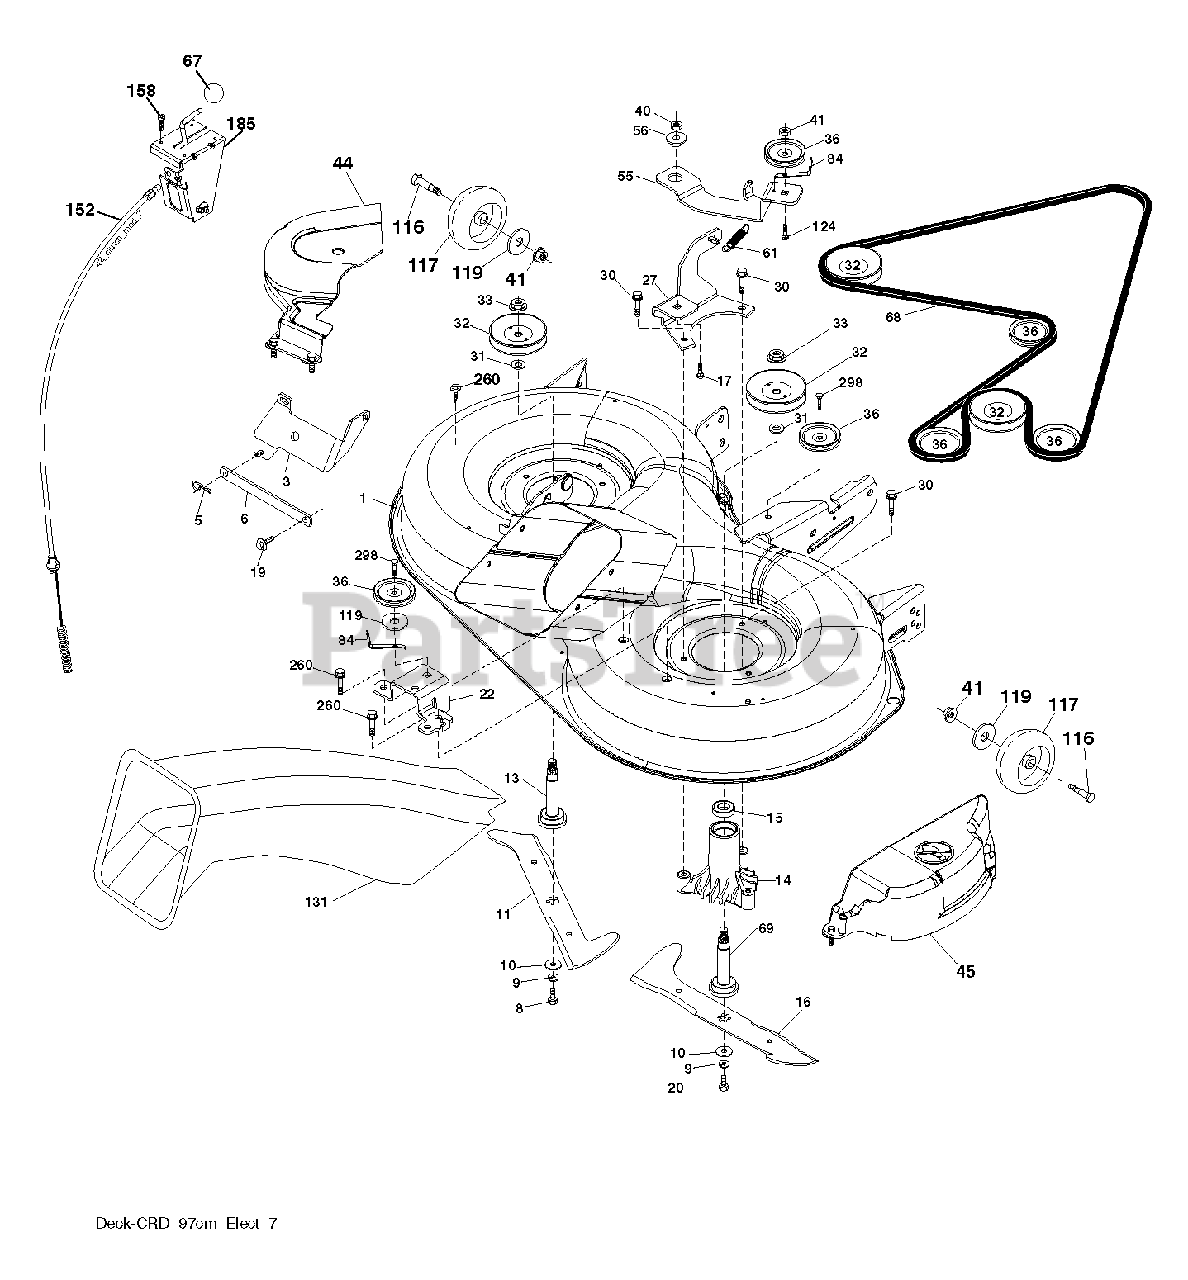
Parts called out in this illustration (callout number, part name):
1	DECK.WLDT.97.CRD.2GWB
3	BRACKET.ASM.BAR.SWAY.CHASS
5	RETAINER-SPRNG RB
6	BAR SWAY
8	Bolt, 3/8-24 X 1.25 Gr8
9	LOCKWASHER
11	BLADE.3N1.LH.CRD.97
13	SHAFT ASM VENT
16	BLADE.3N1.RH.CRD.97
17	BOLT.3/8-14X1.25
19	BOLT SHD 5/16-18
20	BOLT.3/8-24X1.25GR8. LHTHRD
22	BRACKET.SUPT.IDLER.REAR.RH
27	BRACKET.ASM.SUSP.REAR.RH.
30	SCREW, WASHER HEAD
31	WASHER.SPACER.MANDREL
32	PULLEY MANDREL
33	NUT.FLANGE.LOCK.TOP
36	PULLEY.IDLER.4.25
40	LOCKNUT
41	NUT LOCK FLG 3/8-16 UNC
56	SPACER.RETAINER.MOWER
67	KNOB T (3/8 HOLE)
68	BELT.DRIVE.CRD.97.2010
69	SHAFT.ASM.W/LWR.BRG.RH.THREAD
84	KEEPER, BELT IDLER
116	BOLT.SHOULDER.3/8-16X3-5/8
117	WHEEL. GUAGE RALLY
124	BOLT.3/8-16X1.50
158	SCREW
185	HEAD ASM. CABLE CLUTCH
260	SCREW 3/8-16X1/2
298	SCREW LT
